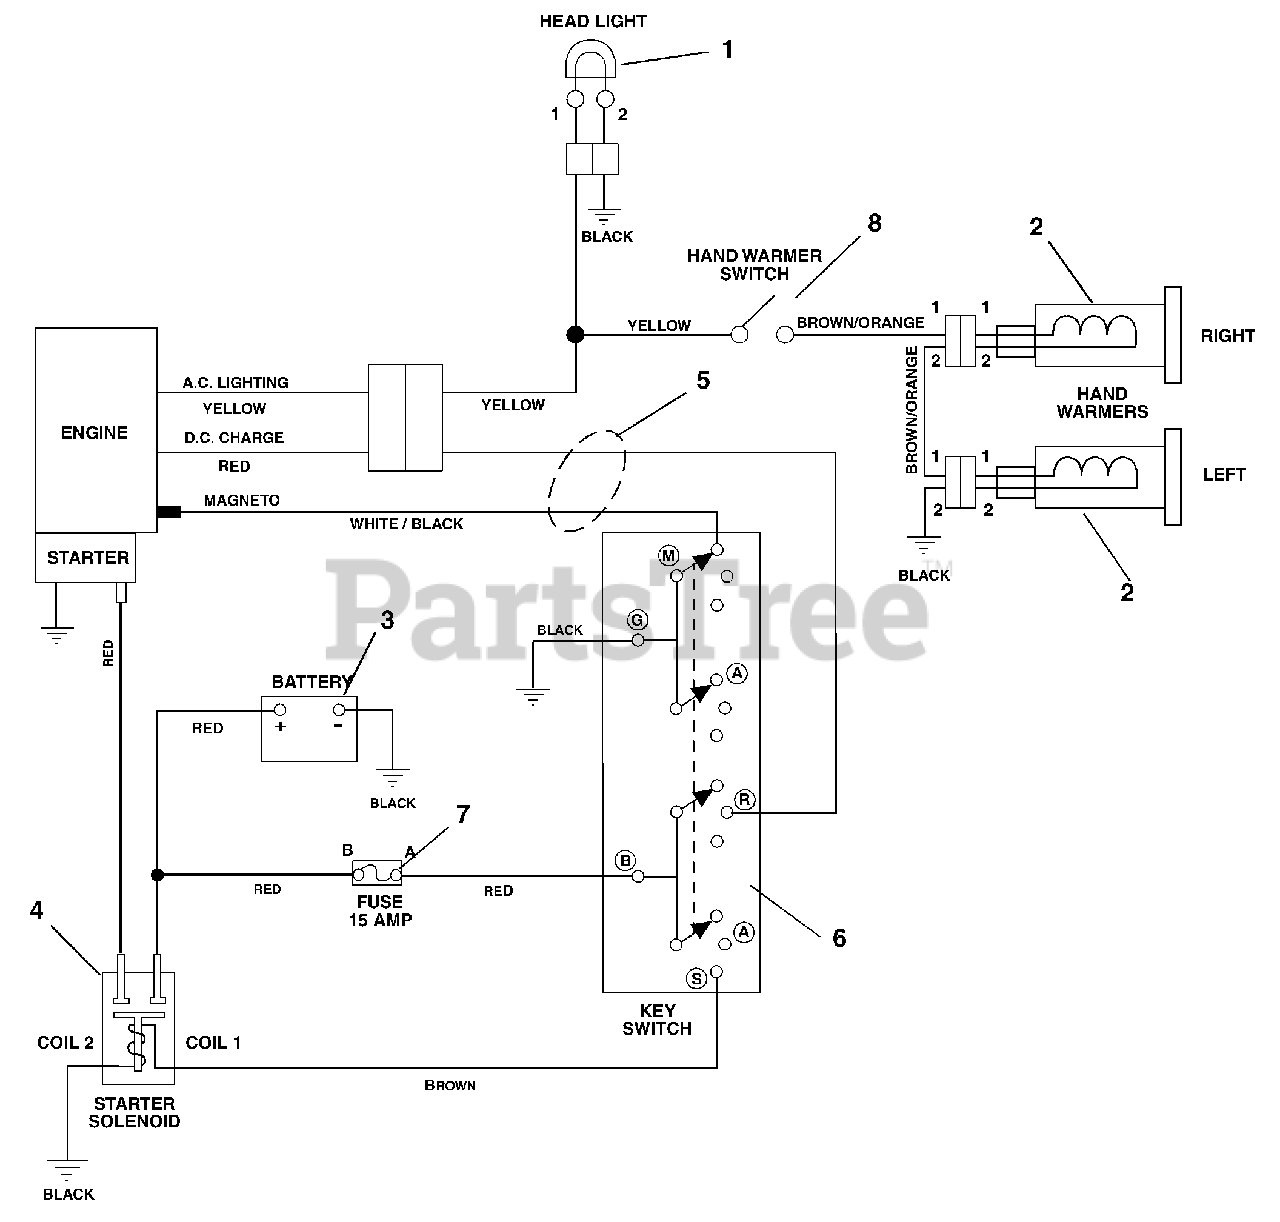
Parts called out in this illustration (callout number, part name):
1	HEADLAMP, OVAL W/ 1156 BULB
2	WARMER, HAND W/TERMINAL
3	Battery
4	SOLENOID
5	HARNESS, WIRING-LT,HG,12V
6	SWITCH ASSEMBLY
7	FUSE, 15 AMP.
8	SWITCH, ON/OFF
